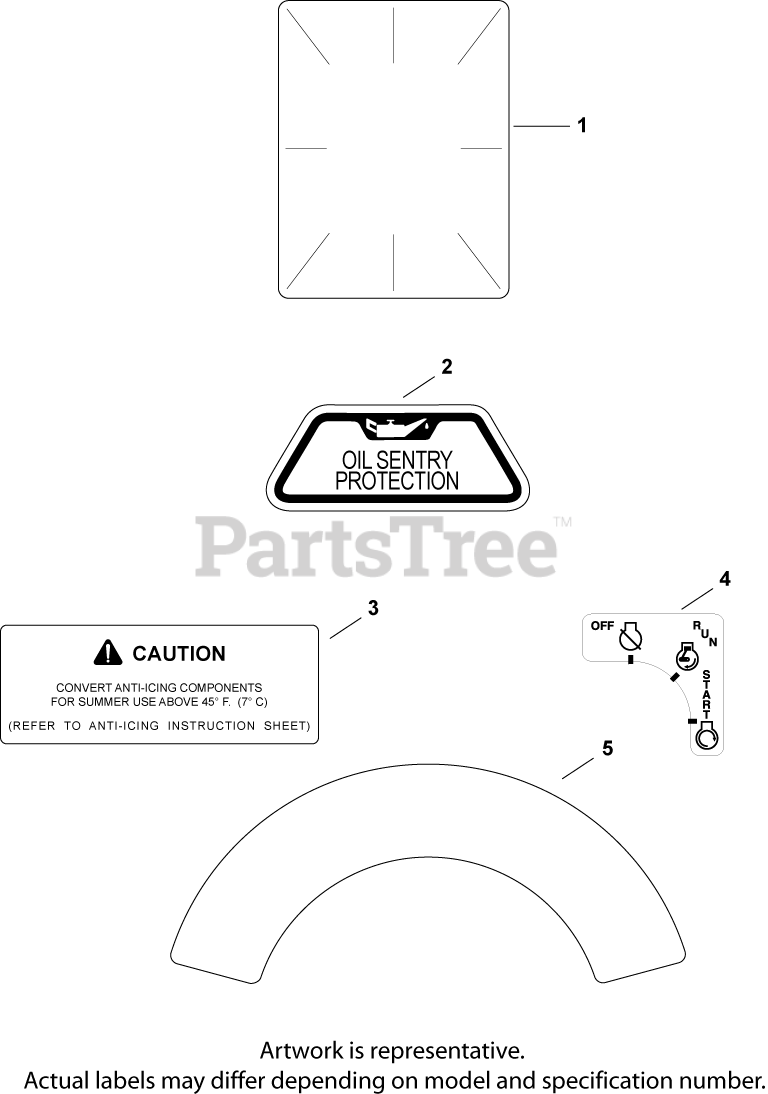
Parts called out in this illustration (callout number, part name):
1	DECAL, CLEAR LAMINATE USE 25 113 70-S
2	DECAL, OIL SENTRY - (#DSC)
3	DECAL, ANTI-ICING
4	DECAL, KEY SWITCH
5	DECAL, 20 HP - DISCONTINUED
